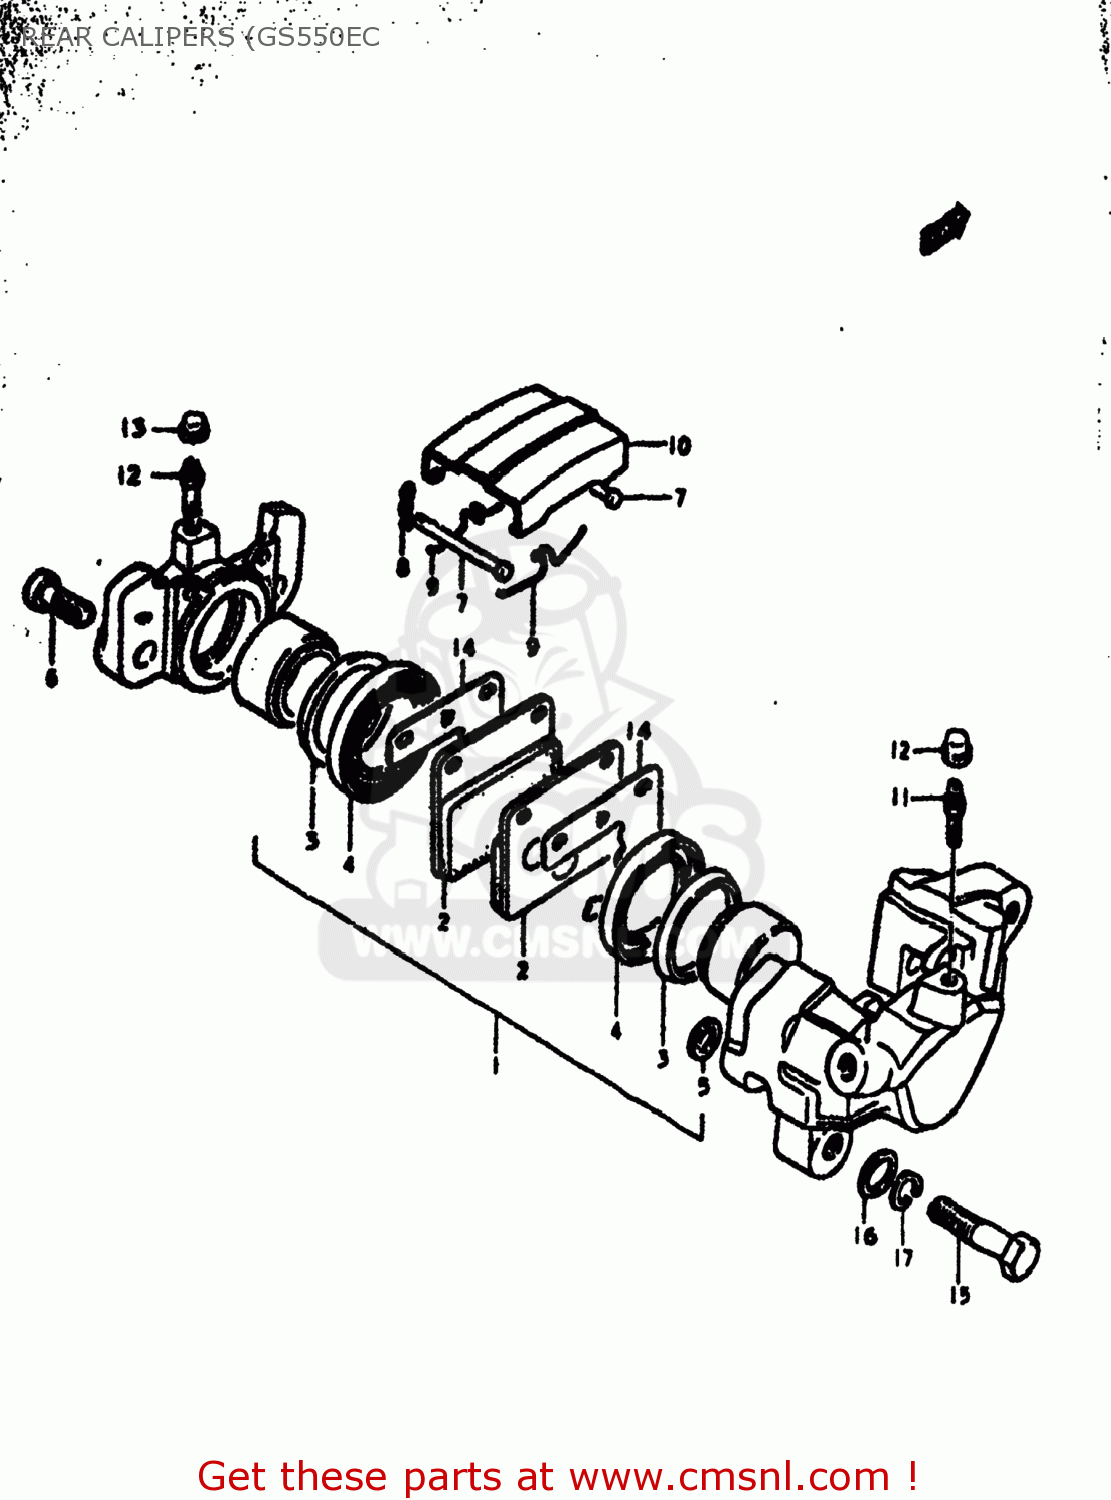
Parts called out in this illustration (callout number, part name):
1	PISTON SET
2	PAD,BRAKE
3	SEAL,PISTON
4	BOOT,PISTON
5	SEAL,PISTON
6	BOLT,HOUSING
7	PIN,PAD
8	CLIP,PAD PIN
9	SPRING
10	COVER,DUST
11	BLEEDER
12	BREATHER
13	CAP,BREATHER
14	SHIM,RR CALIPER
15	BOLT 10X34
16	WASHER
17	LOCK WASHER
